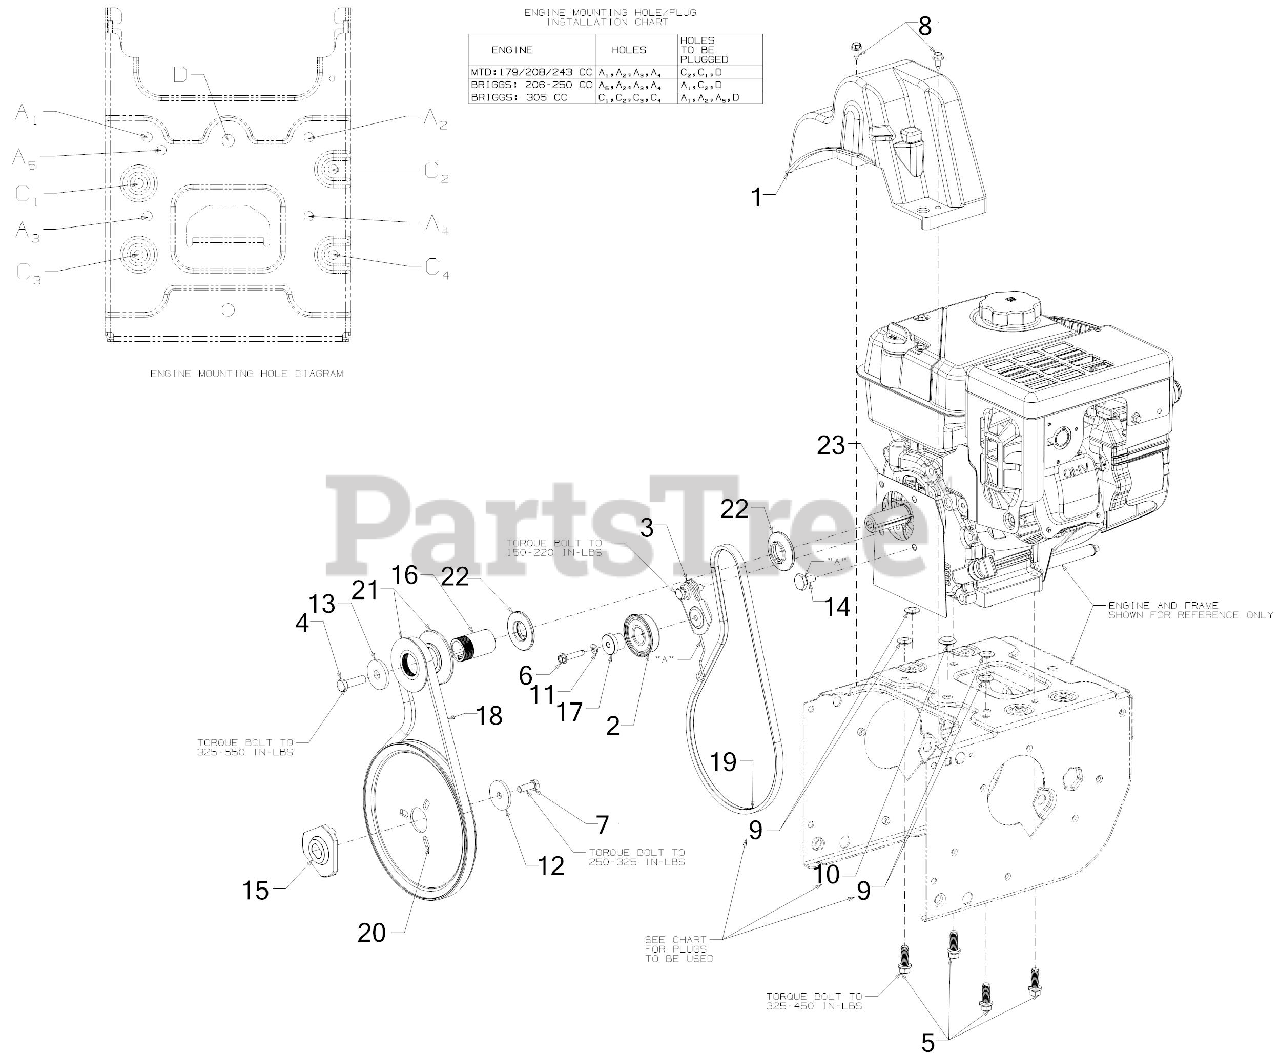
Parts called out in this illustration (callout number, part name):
1	BELT COVER (SMALL BLOCK)
1	HEX SCREW #12-16 x .50
2	IDLER PULLEY ASSEMBLY
3	IDLER ASSEMBLY
4	SCREW 3/8-24X1.25
5	SCREW 3/8-16 x 1
6	SCREW 1/4-20 x 1.25
7	SCREW 5/16-24 x .875 GR5
8	SCREW 1/4-20X.625
9	PLUG-3/8 DIA ID x 3/32
10	PLUG-1/2 ID x 3/32
11	LOCK WASHER
12	FLAT WASHER
13	FLAT WASHER .45 x 1.5 x .172 HT
14	SHOULDER SCREW
15	ADAPTER PULLEY .75 DIA W/DD
16	PULLEY SPACER
17	SHOULDER SPACER
18	V-BELT .500 x 35.
19	V-BELT 3L x 34.18
20	AUGER PULLEY
21	HALF PULLEY 4L V x 2.6 OD
22	HALF PULLEY-3/8 V x 1.7160
23	COVER PLATE
